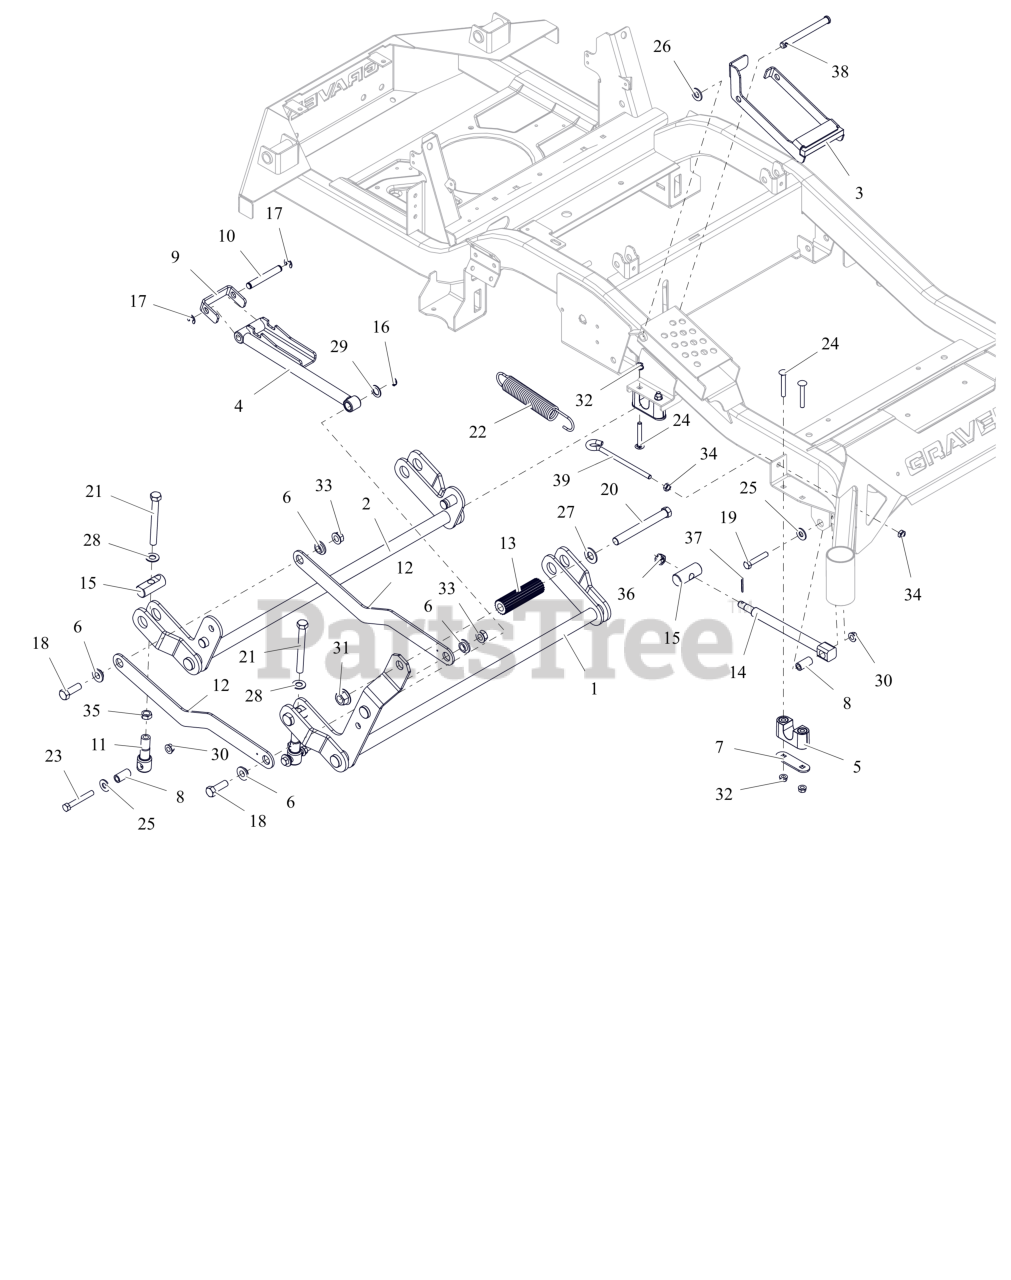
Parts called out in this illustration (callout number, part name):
1	WLDMT, FRONT DECK LIFT PIVOT
2	WLDMT, REAR DECK LIFT PIVOT
3	WLDMT, HOC TRANSFER LOCK (BLACK)
4	WLDMT, HOC LIFT ARM (BLACK)
5	ASM-BUSHING, DECK LIFT
6	BSHG-FLG .515X.750X.310X1.120
7	PLATE, BEARING SUPPORT
8	SPACER, DECK LEVELING
9	BRKT, HOC LINE
10	ROD, HOC PIVOT
11	LINK, DECK LIFT FORMED
12	LINK, DECK
13	ROD, FOOT PEDAL (BLACK)
14	DRAG,LINK-HD
15	PIN, DECK LIFT
16	RG-RTNG-EXT .625X.050
17	RG-RTNG-EXT .500X.042 (E)
18	BLT,HEX .50-13X1.50 G5 ZCC
19	BLT,HEX .38-16X2.00 G5 ZCC
20	BLT, HEX .62-11X5.50 G5 FBP
21	BLT, HEX .50-13X4.50F G8 ZCC
22	SG-TENS .162X1.25X8.25 WLD 25
23	BLT, HEX .38-16X2.75 G8 ZCC
24	BLT, RHSSN.31-18X2.25 G5 ZCC
25	WSHR,FLT .438X1.00X.083 ZCC
26	WSHR,FLT .531X1.062X.095 ZCC
27	WSHRFLT 5/8SAE CARBHARD FBP
28	WSHR, FLT .557X1.040X.102 ZCC
29	WSHR, FLT .630X1.005X.062 ZCC
30	NUT-LK-TOP-FLG .38-16 ZC120
31	NUT,FLG-TOP LK .625-11 FBP
32	NUT,LK-CTR-FLG .31-18 GF ZCC
33	NUT-LK-TOP-FLG .500-13 GF ZCC
34	NUT-JAM .375-16 G2 ZCC
35	NUT-JAM .500-13 G2 ZCC
36	NUT-SL .50-13
37	PIN,CTR.12X1.25EXTPRSQCT ZC120
38	PIN, SLIC-.500X4.97X4.55 -ZC
39	BOLT,.38-16 X 5.25-.62 DIA EYE
